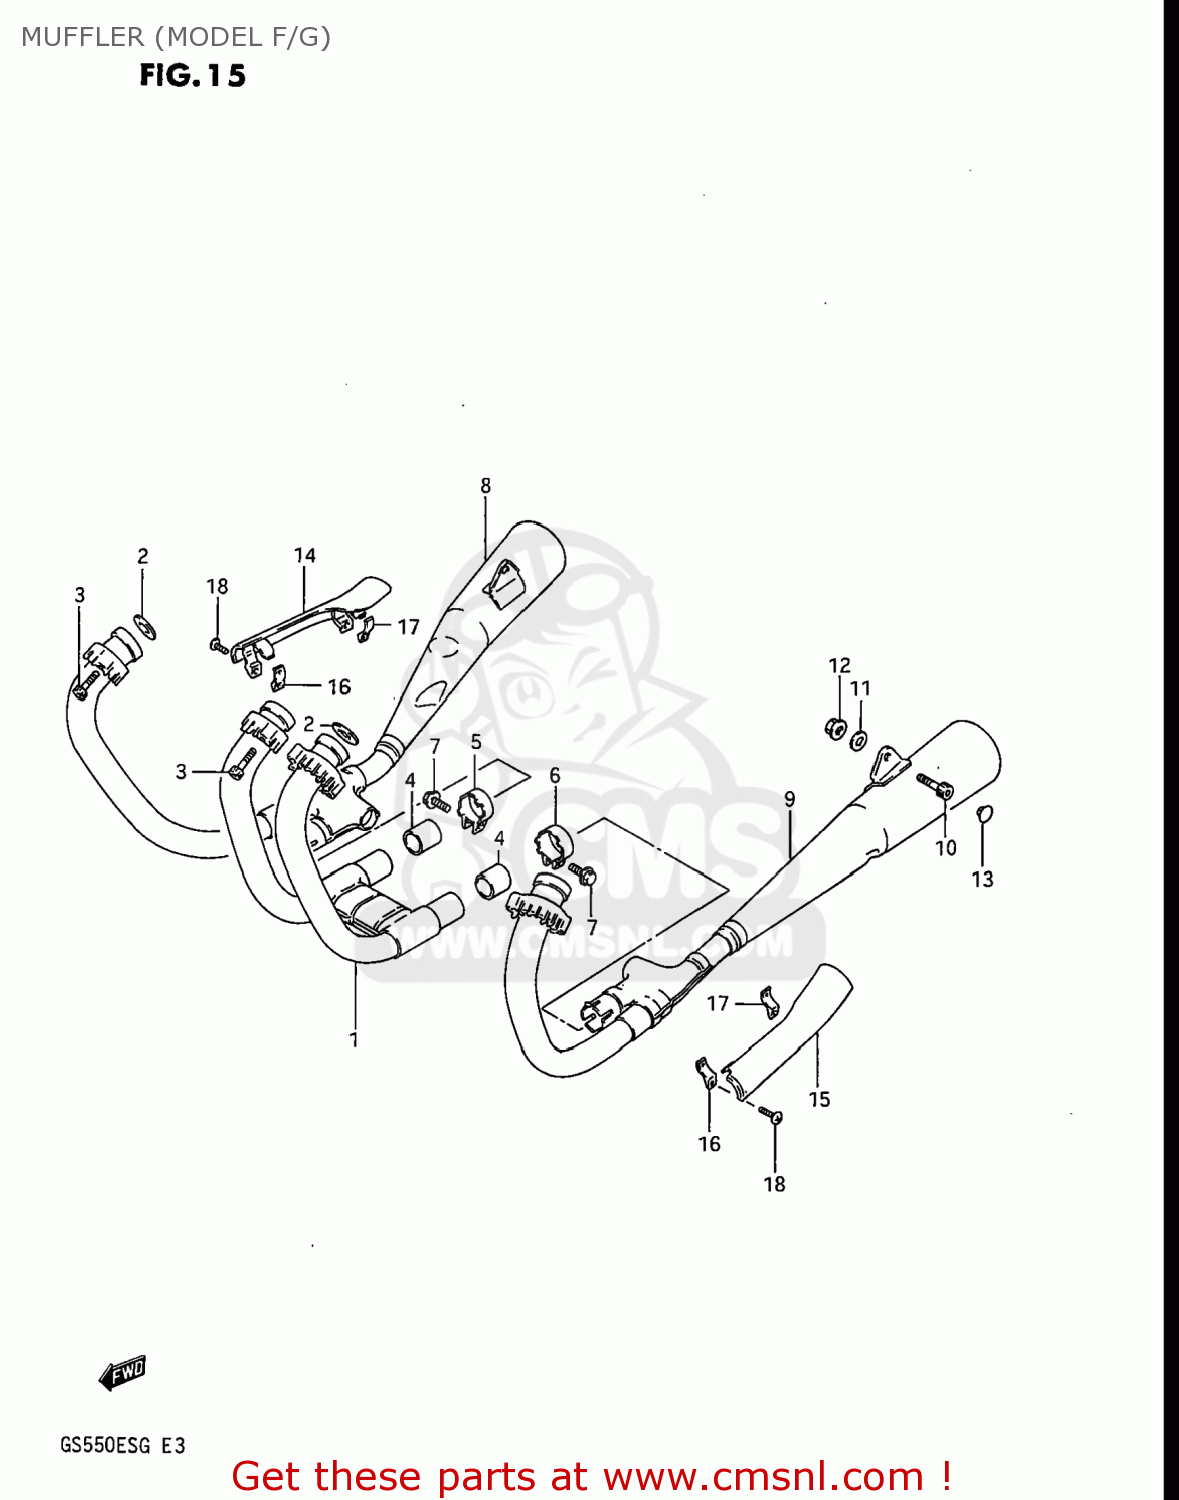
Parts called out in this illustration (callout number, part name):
1	PIPE,EXHAUST
2	GASKET,EXHAUST PIPE (NAS)
3	BOLT
4	CONNECTOR,MUFFLER
5	CLAMP,MUFFLER CONNECTOR
6	CLAMP,MUFFLER CONNECTOR
7	BOLT
8	MUFFLER ASSEMBLY
9	MUFFLER ASSEMBLY
10	BOLT
11	WASHER(10.5X20X3.2)
12	NUT
13	CAP
14	COVER,MUFFLER,RIGHT
15	COVER,MUFFLER,LEFT
16	CLAMP,MUFFLER COVER
17	CLAMP,MUFFLER COVER
18	SCREW
